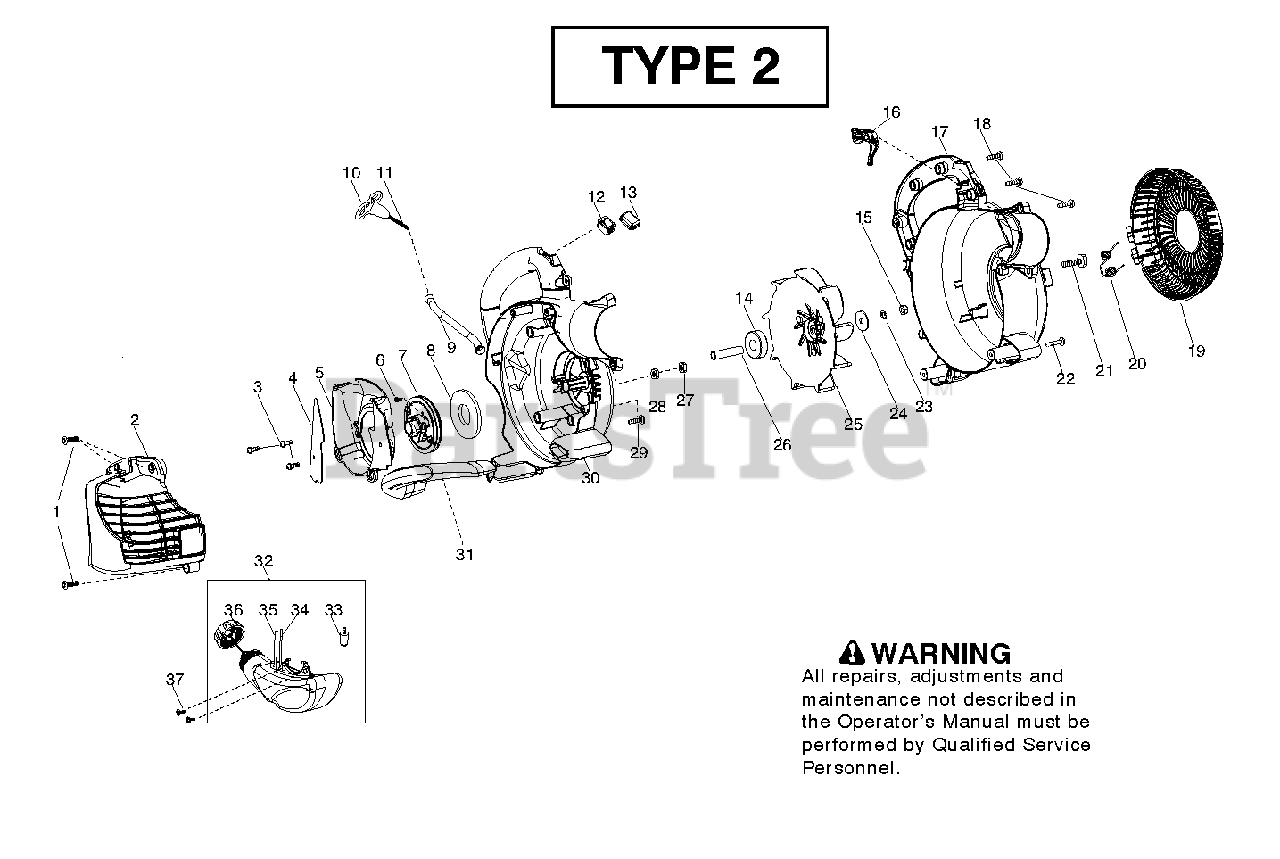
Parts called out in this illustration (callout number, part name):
2	ASSY COVER ENGINE
4	SHIELD BAFFLE
6	SCREW SEMS TOOTHED WASHER
7	KIT STARTER PULLEY
8	KIT STARTER SPRING
9	TUBE STARTER ROPE
10	HANDLE STARTER BLK
12	KIT SWITCH
13	PROTECTOR, SWITCH
16	TRIGGER THROTTLE RED
17	COVER
19	DOOR VAC BLACK
20	SPRING VAC DOOR
22	SCREW #10 PLASTITE 1.362
24	WASHER, IMPELLER
25	ASSY IMPELLAR HUB
26	SPACER FLYWHEEL
30	ASSY SCROLL RIGHT
31	HANDLE VAC BLACK
32	Fuel Tank Assembly, Non Low Perm St
33	FUEL PICK-UP ASSY
36	ASSY FUEL CAP W/RETAINER
37	SCREW FUEL TANK RETAINER
